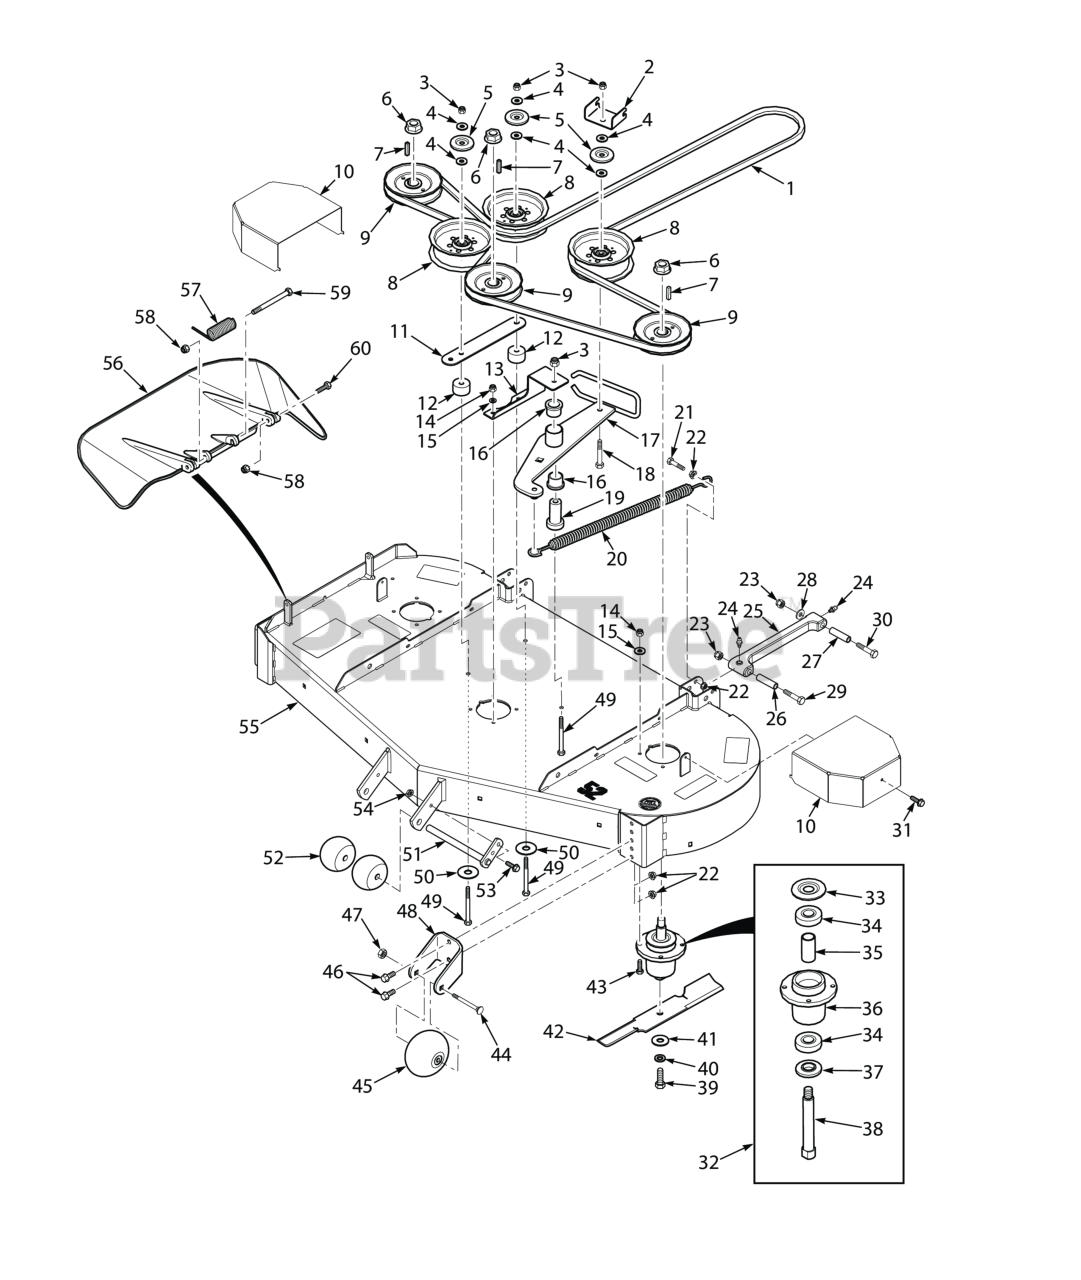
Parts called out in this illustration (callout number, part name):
1	Belt, Cutter Deck - 61
2	Bracket, Belt Guide
3	HEX NUT, ELASTIC STOP LOCK, 3/8-16
4	Flatwasher, 3/8 (.391 x .938 x .105 HD) Grade 8
5	Quick Pin, 5/16" Dia.
6	Nut, 3/4-16 Spriral Lock
7	Key, 1/4 x 1/4 x 1.25" Pulley Mtg.
8	Pulley, 5" Idler
9	Pulley, 6.32" OD - 25mm Bore
10	Belt Cover
11	Brace, Pulley
12	Spacer, Idler Pulley
13	Support, Idler Pivot
14	Lock Nut, 5/16-18 Elastic Stop Grade 8
15	Lockwasher, 5/16 (.317 x .586 x .078) Helical Spring
16	Bearing, Plastic
17	Idler Arm (incl. item #15)
18	Capscrew, Hex Head 3/8-16 x 2-1/2"
19	Pivot, Idler
20	Spring, Cutter Deck Idler
21	Bolt, Hex Head 3/8-16 x 1-1/2" Grade 8 Black
22	NUT, 3/8-16 SERRATED FLANGE HEX HEAD
23	HEX LOCKNUT, ELASTIC STOP, 1/2-13
24	GREASE FITTING, STR. 1/4-28 SELF TAP.
25	Pusharm Assembly, LH
25	Pusharm Assembly, RH
26	Spacer, Pusharm - Deck
27	Spacer, Pusharm - Axle
28	Flatwasher, 1/2 - .531 x 1.062 x .095
29	Bolt, Hex Head 1/2-13 x 3-1/2"
30	Bolt, Hex Hd. 1/2-13 x 2-1/2" (lower)
31	Screw, 3/8-16 x 3/4"
32	Spindle Assembly
33	Debris Shield
34	Bearing
35	Spacer, Bearing
36	Spindle Housing Assembly
37	Protector, Bearing
38	Shaft, Spindle
39	Bolt, Hex Head 5/8-11 x 1-1/2"
40	Lockwasher, 5/8" Spring
41	Flatwasher, 5/8-.688 x 1-3/4 x .134 HD
42	Cutter Blade, 21" Standard
43	Bolt, Hex Head 5/16-18 x 1-1/2" Grade 8
44	Bolt, Hex Head 3/8-16 x 3-1/2"
45	Bolt, Carriage 3/8-16 x 4"
46	Capscrew, 3/8-16 x 1.0" Serrated Flange Hex Hd
47	Bolt, Hex Head 3/8-16 x 1" Ser. Flg.
48	Bracket, Anti-Scalp, (Black)
49	Bolt, Hex Head, 3/8-16 x 3-1/2"
50	Flatwasher, 3/8-.406 x 2.25" x .1875
51	Shaft Weldment, Guide Roller
52	Wheel, Anti-Scalp
53	Bolt, Heax Head 5/16-18 x 1" (48V / 52V)
54	Nut, Flange Head Elastic Stop 5/16-18
55	Cutter Deck w/Decals
56	Discharge Chute Assembly
57	Spring, Discharge Chute
58	HEX NUT, ELASTIC STOP LOCK, 5/16-18
59	Bolt, 5/16-18 x 4-3/4" Hex Head
60	Bolt, Hex Head 5/16-18 x 1-1/2" - Front
